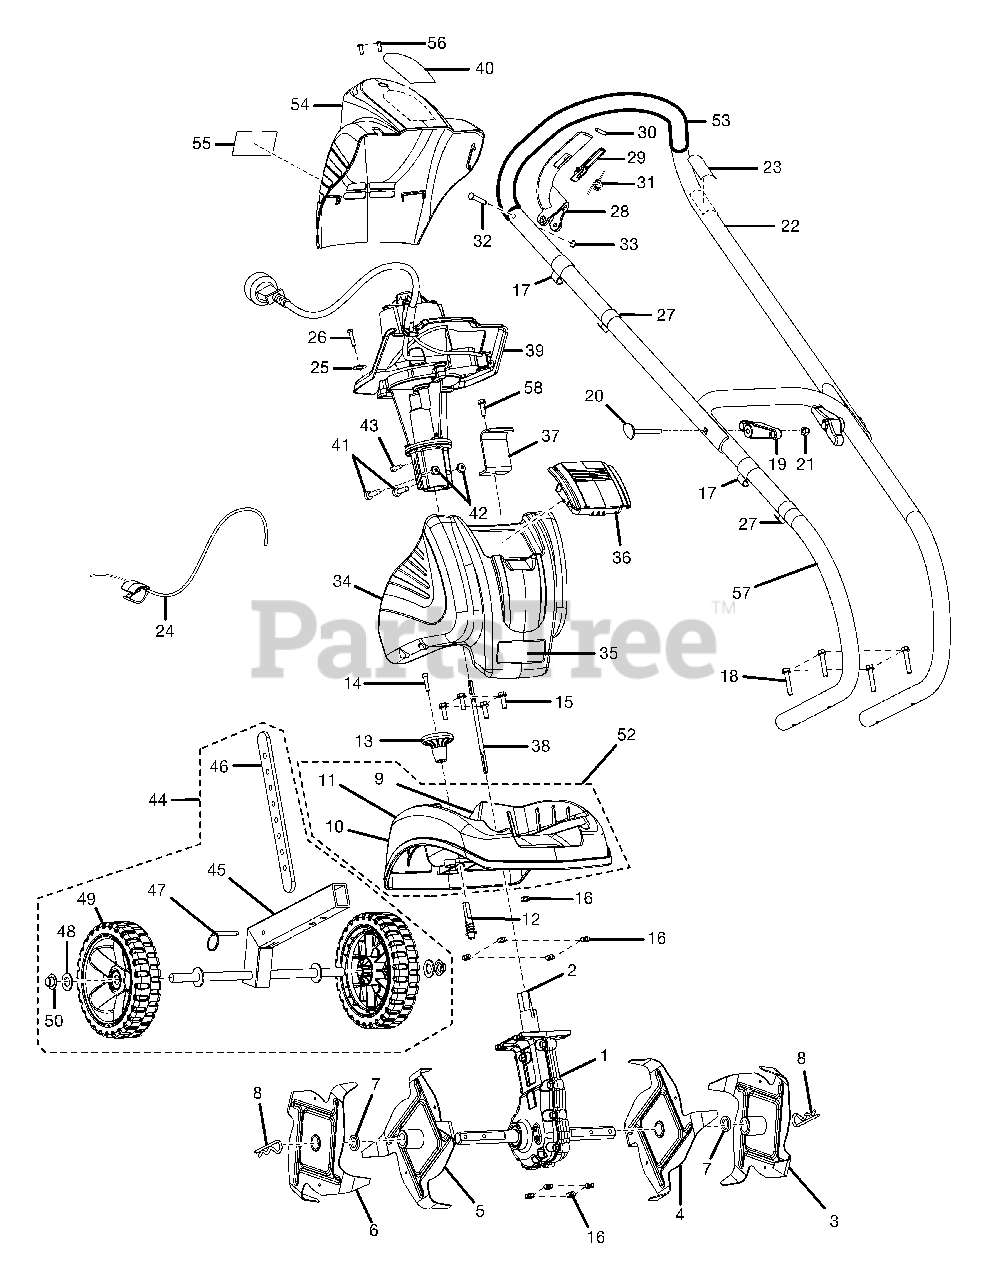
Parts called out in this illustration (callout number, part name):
1	GEAR BOX ASSY W/TUBE AND LINER
2	LINER-HELIX (47 mm)
3	TINE ASSEMBLY (A)
4	TINE ASSEMBLY (B)
5	TINE ASSEMBLY (C)
6	TINE ASSEMBLY (D)
7	FELT WASHER
8	CLEVIS CLIP
9	WARNING LABEL (BACK LEFT)
10	WARNING LABEL (BACK RIGHT)
11	WARNING LABEL (FOOT)
12	RECEIVER RETAINER ASSEMBLY
14	SCREW (M5 x 16 mm SOC. WASHER HD. CAP)
15	BOLT (1/4-20 x 3/4 in. HEX HD.)
16	LOCK NUT (1/4-20)
17	PLASTIC CLIP
18	BOLT (HANDLE) (1/4-20 x 1-1/2 in. HEX HD.)
19	KNOB (1/4-20)
20	CARRAIGE BOLT (1/4-20 x 2-1/4 in.)
21	NUT-ACORN, CENTERLOCK (1/4-20)
22	HANDLE, UPPER ASSEMBLY W/GRIP AND LABEL
23	BOOM LABEL
24	THROTTLE CABLE ASSEMBLY
25	WASHER
26	SCREW (M4 x 16 mm)
29	LOCK OUT LEVER
32	CLEVIS PIN
33	RETAINING RING
34	TANK, BALLAST ASSEMBLY
35	LOGO LABEL
37	MOUNTING BRACKET
38	DRIVE SHAFT
39	MOTOR AND PINION ASSEMBLY
40	LABEL, ELECTRIC AMP LOGO
41	SCREW (M5 x 19 mm SOC. HD. CAP)
42	SQUARE NUT (M5)
43	SCREW (8-16 x 1/2 in. PAN HD.)
44	WHEEL/DRAG STAKE ASSEMBLY
45	FRAME ASSEMBLY
46	DRAG STAKE
47	HITCH PIN
49	WHEEL ASSEMBLY
50	PUSH CAP NUT (1/2 in.)
52	TINE SHIELD ASSEMBLY
54	REAR HOUSING ASSEMBLY
55	DATA LABEL
56	SCREW (M4 x 13 mm TF.)
57	LOWER HANDLE ASSEMBLY
58	BOLT (1/4-20 X 5/8 in.)
